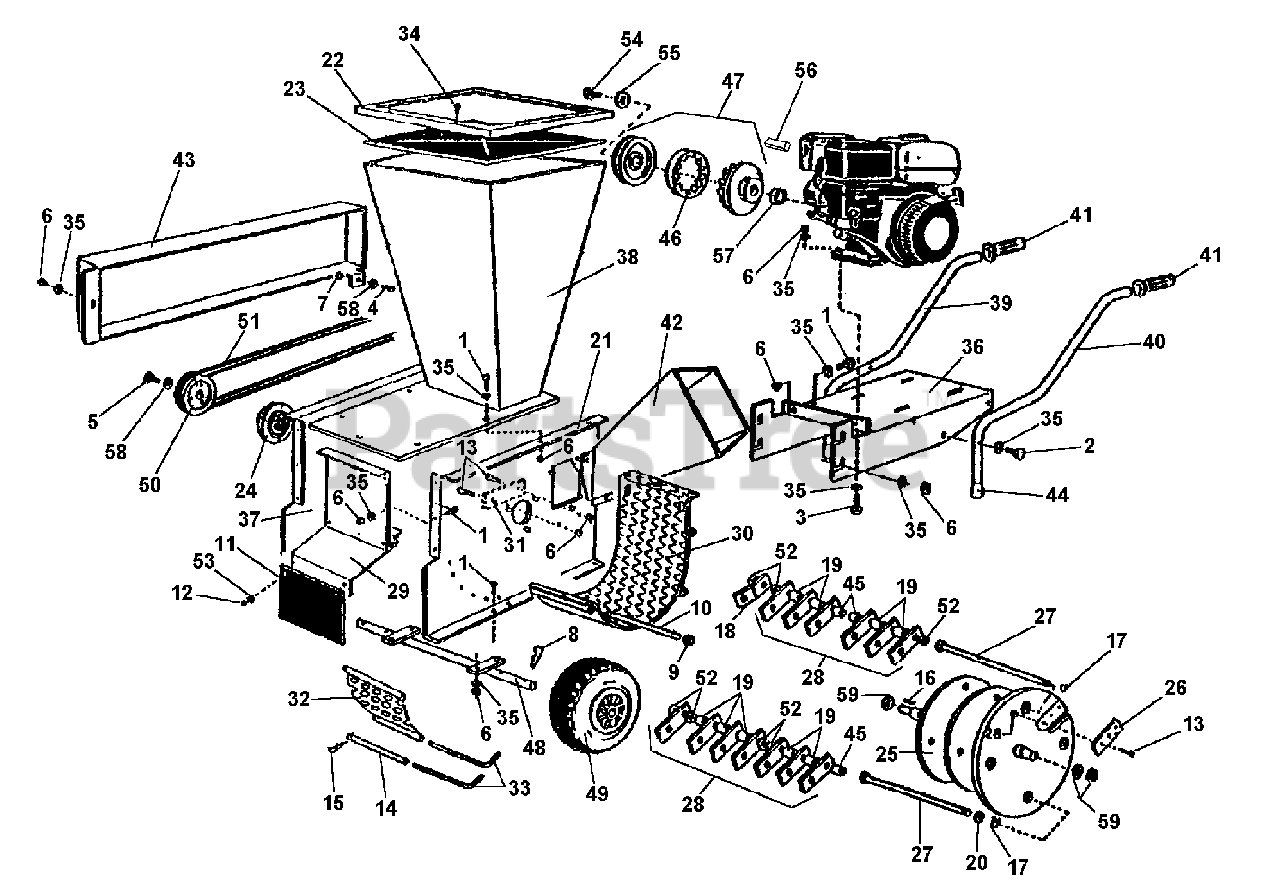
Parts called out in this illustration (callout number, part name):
1	SCREW, M8x20
2	SCREW, M8x40
3	SCREW, M8x50
4	SCREW, M10x30
5	SCREW M10X25
6	Nut, Self Locking, M8
7	NUT, SELF LOCKING, M10
12	Rivet, 4.9x16
13	Counter Sunk Bolt, M8x25
21	Right Side Wall
22	Deflector Support
23	Hopper Flap
24	Support & Bearing
27	Shaft Hammer W/Snap Ring
29	Deflector, Discharge
30	Panel, Bottom
31	Blade Stationary
34	SCREW, M6.3x19
36	Engine Plate
37	Left Side Wall
39	RIGHT HANDLE STEM
40	LEFT HANDLE STEM
41	Handle Knob
42	Chipper Chute
43	Belt Crankcase
44	Rubber Foot
46	Clutch Lining
47	Clutch Assembly
48	Wheel Support
50	Pulley Assemply
